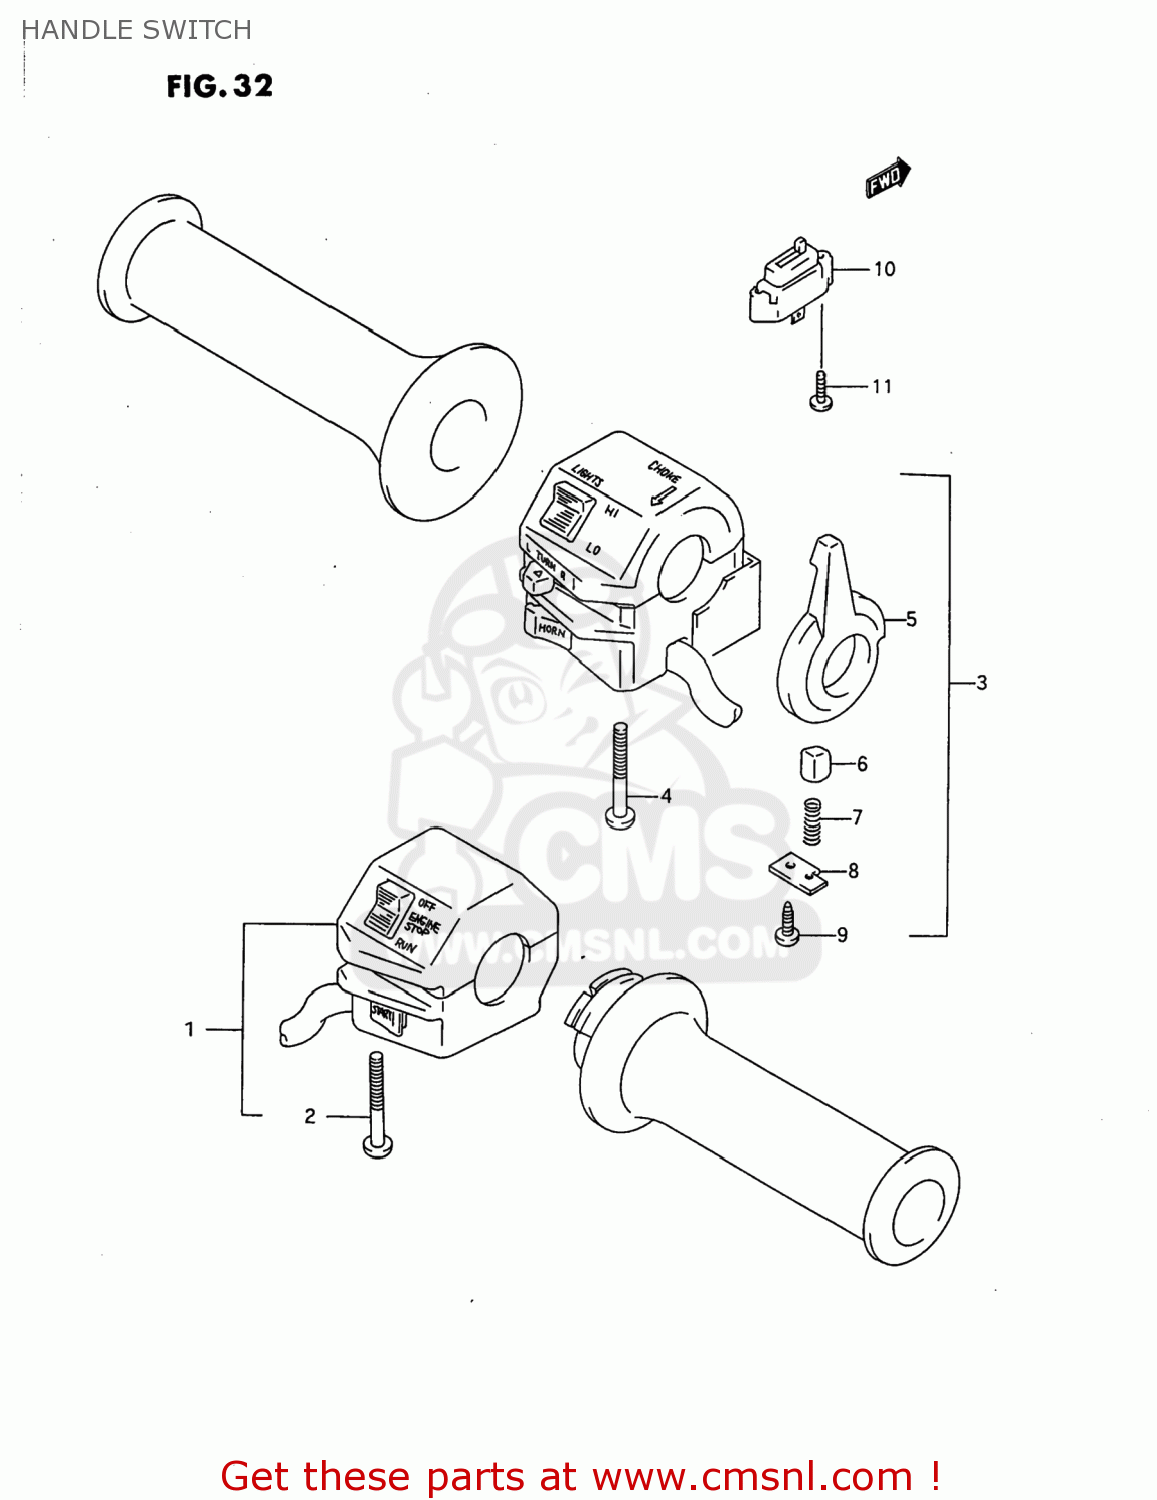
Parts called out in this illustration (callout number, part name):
1	SWITCH ASSEMBLY,HANDLE,RIGHT
2	SCREW, 5X45
3	SWITCH ASSY, HANDLE,LH
4	SCREW, 5X45
5	LEVER,CHOKE
6	PIECE,SLIDE
7	SPRING
8	PLATE
9	SCREW, TRUNK BOX
10	SWITCH ASSY,CLUTCH
11	SCREW
